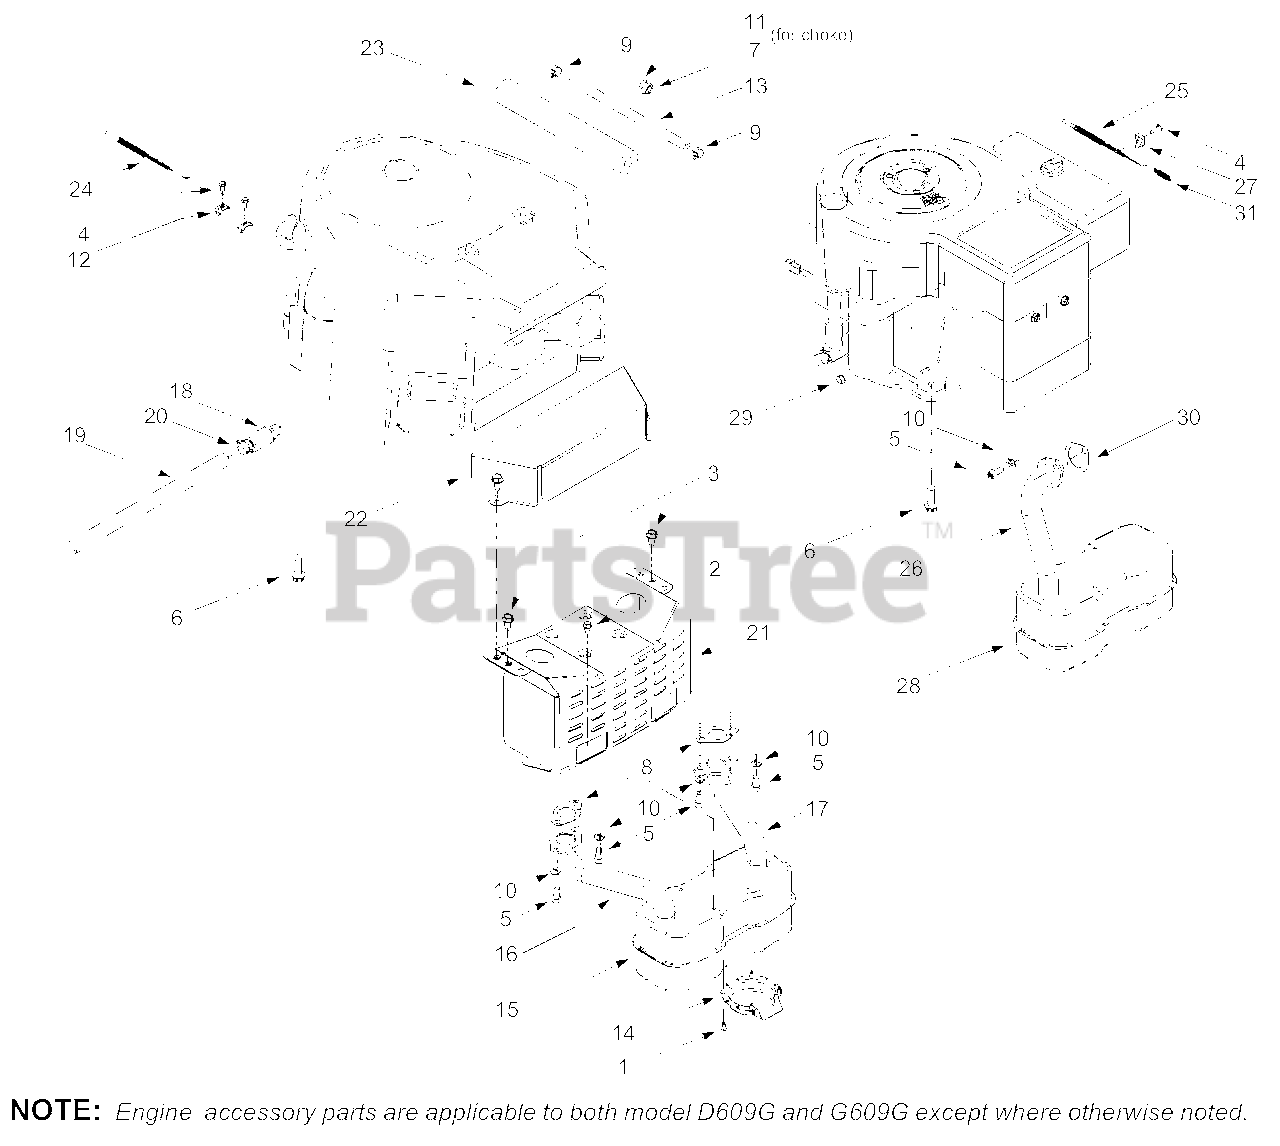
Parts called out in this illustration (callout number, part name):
1	Self-tapping Screw, #8-18 x .5
2	Self-tapping Screw, 1/4-20 x .5
3	Self-tapping Screw, 5/16-18 x .625
4	Screw, #10-32 x .625
5	Socket Cap Screw, 5/16-18 x .625
6	Self-tapping Screw, 3/8-16 x 1.25
7	Hex Nut, 3/8-16 (Model G609G)
8	Exhaust Gasket (Model G609G)
9	Hose Clamp
10	Lock Washer, 5/16
11	Flat Washer (Model G609G)
12	Casing Clamp (Model G609G)
13	Fuel Line Hose
14	Muffler Deflector
15	Muffler, Twin Inlet (Model G609G)
16	RH Exhaust Pipe (Model G609G)
17	LH Exhaust Pipe (Model G609G)
18	Oil Drain Valve
19	Oil Drain Hose
20	Oil Drain Cap
22	Engine Heat Shield (Model G609G)
23	Foam (fits over fuel line)
24	Throttle Cable (Model G609G)
25	Throttle Cable (Model D609G)
26	Exhaust Pipe (Model D609G)
27	Casing Clamp (Model D609G)
28	Muffler, Single Inlet (Model D609G)
29	Hex Sems Nut, 1/4-20 (for starter cable)
30	Exhaust Gasket (Model D609G)
